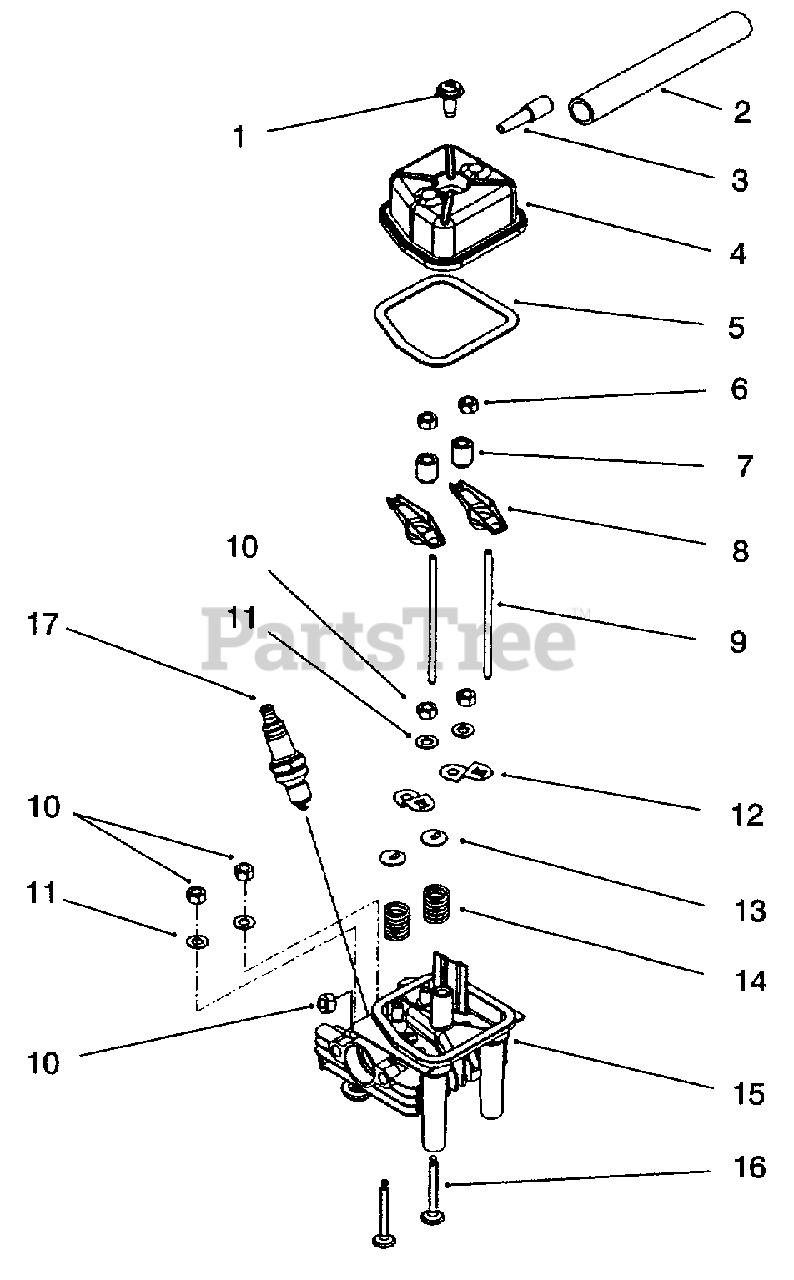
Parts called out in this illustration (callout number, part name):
1	Screw-Valve Cover
2	Hose-Breather
3	Breather Assembly
4	Cover-Valve
5	Gasket-Valve Cover
6	Nut-Rocker Adjusting
7	Pivot-Rocker Arm
8	Arm-Rocker
9	Rod-Push
10	Nut-Hex
12	Guide-Push Rod
13	Retainer-Valve Spring
14	Spring-Valve
15	Head-Cylinder
17	Spark Plug
